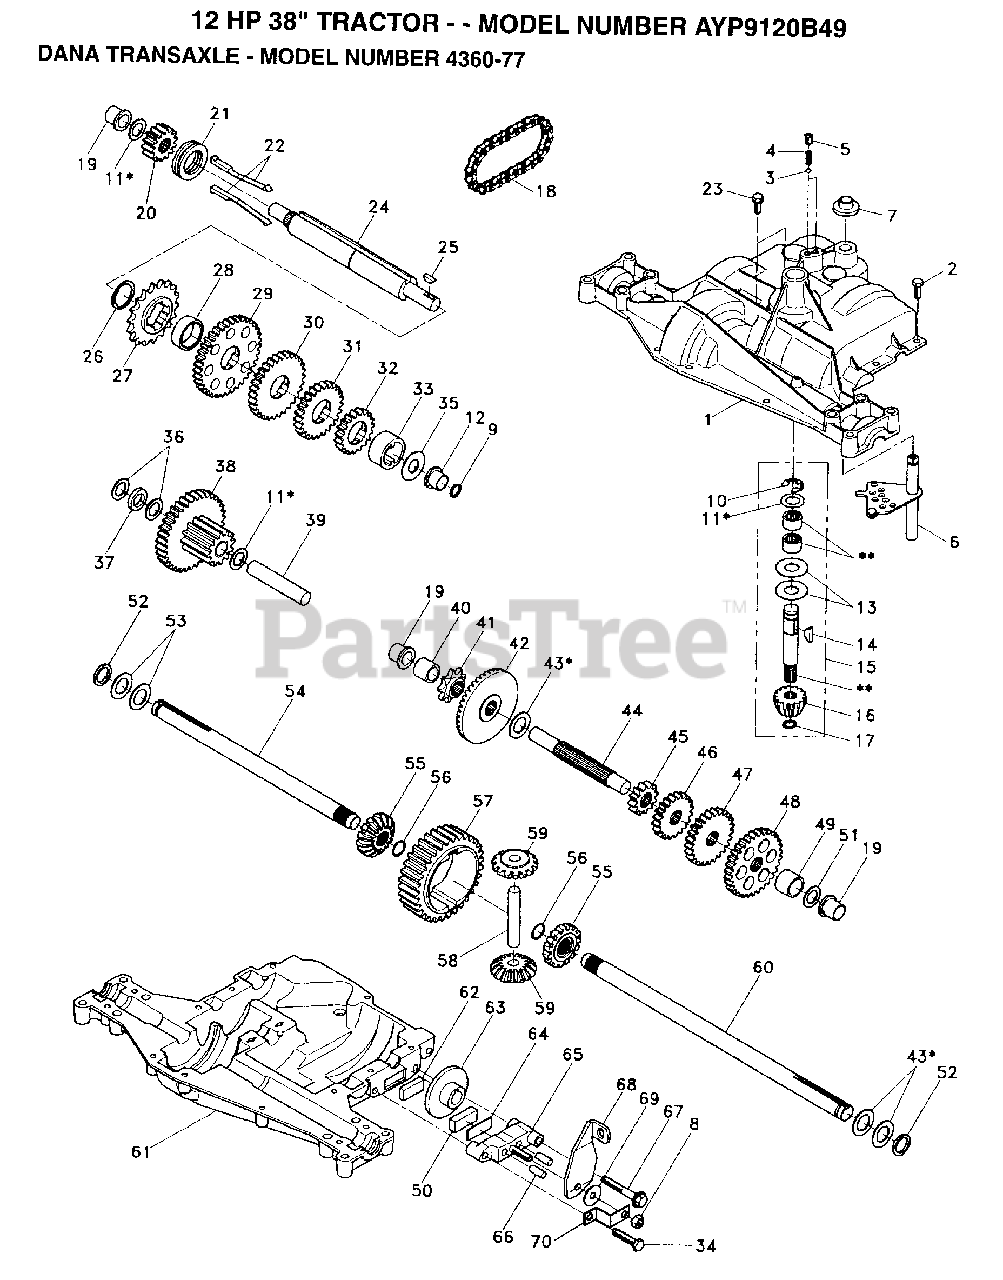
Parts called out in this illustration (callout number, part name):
1	HOUSING, UPPER
3	BALL, DETENT
4	SPRING, DETENT
5	SCREW, SET
6	SHIFTER ASSEMBLY
7	BOOT, SHIFTER
8	LOCKNUT 5/16-24
10	RING, RETAINING
11	ASSY, KIT, SHIM .625 SHAFT
12	BEARING, FLANGE
13	WASHER, PLAIN .632 X 1.38 X .046
14	KEY, WOODRUFF, #9
15	ASSEMBLY, KIT, INPUT SHAFT
16	PINION, BEVEL, 14 TEETH
17	RING, RETAINING
18	CHAIN, 24 PITCHES
19	BEARING, FLANGE
20	GEAR, SPUR, 14 TEETH
21	COLLAR, CLUTCH
22	ASSEMBLY, KIT, CLUTCH KEYS
23	SCREW TAPPING WITH SEALER
24	SHAFT, INTERMEDIATE
25	KEY, WOODRUFF, #61
26	RING, RETAINING
27	SPROCKET, 18 TEETH
29	GEAR, SPUR, 37 TEETH
30	GEAR, SPUR, 30 TEETH
31	GEAR, SPUR, 25 TEETH
32	SPACER 1.133 X 1.50 X .750
33	GEAR, SPUR, 22 TEETH
34	SCREW TAPPING
35	WASHER, PLAIN .640 X 1.37 X .061
36	WASHER, PLAIN .632 X 1.00 X .026
37	SPACER .630 X 1.00 X .169
38	ASSY GEAR COMB 12&35 TEETH
39	SHAFT, IDLER
40	SPACER .635 X .875 X .755
41	SPROCKET, 9 TEETH
42	GEAR, BEVEL, 42 TEETH
43	ASSY, KIT, SHIM .750 SHAFT
44	SHAFT, DRIVE
45	GEAR SPUR, 12 TEETH
46	GEAR, SPUR, 20 TEETH
47	GEAR, SPUR, 25 TEETH
48	GEAR, SPUR, 31 TEETH
49	SPACER .781 X 1.00 X .750
50	PUCK, FRICTION
51	WASHER, PLAIN .632 X 1.00 X .060
52	WASHER, NEOPRENE
53	WASHER, PLAIN .758 X 1.25 X .031
54	AXLE LEFT HAND
55	GEAR, MITER, 15 TEETH
56	RING, RETAINING
57	GEAR, SPUR, 32 TEETH
58	SHAFT, CROSS
59	GEAR, MITER, 15 TEETH
60	AXLE, R.H.
61	HOUSING, LOWER
62	PUCK, FRICTION
63	DISC, BRAKE
65	JAW, BRAKE
66	PIN, DOWEL
67	SCREW, SELF-TAPPING
68	LEVER ACTUATING
69	WASHER, PLAIN .321 X 1.00 X .055
70	BRACKET, ANTI-ROTATION
